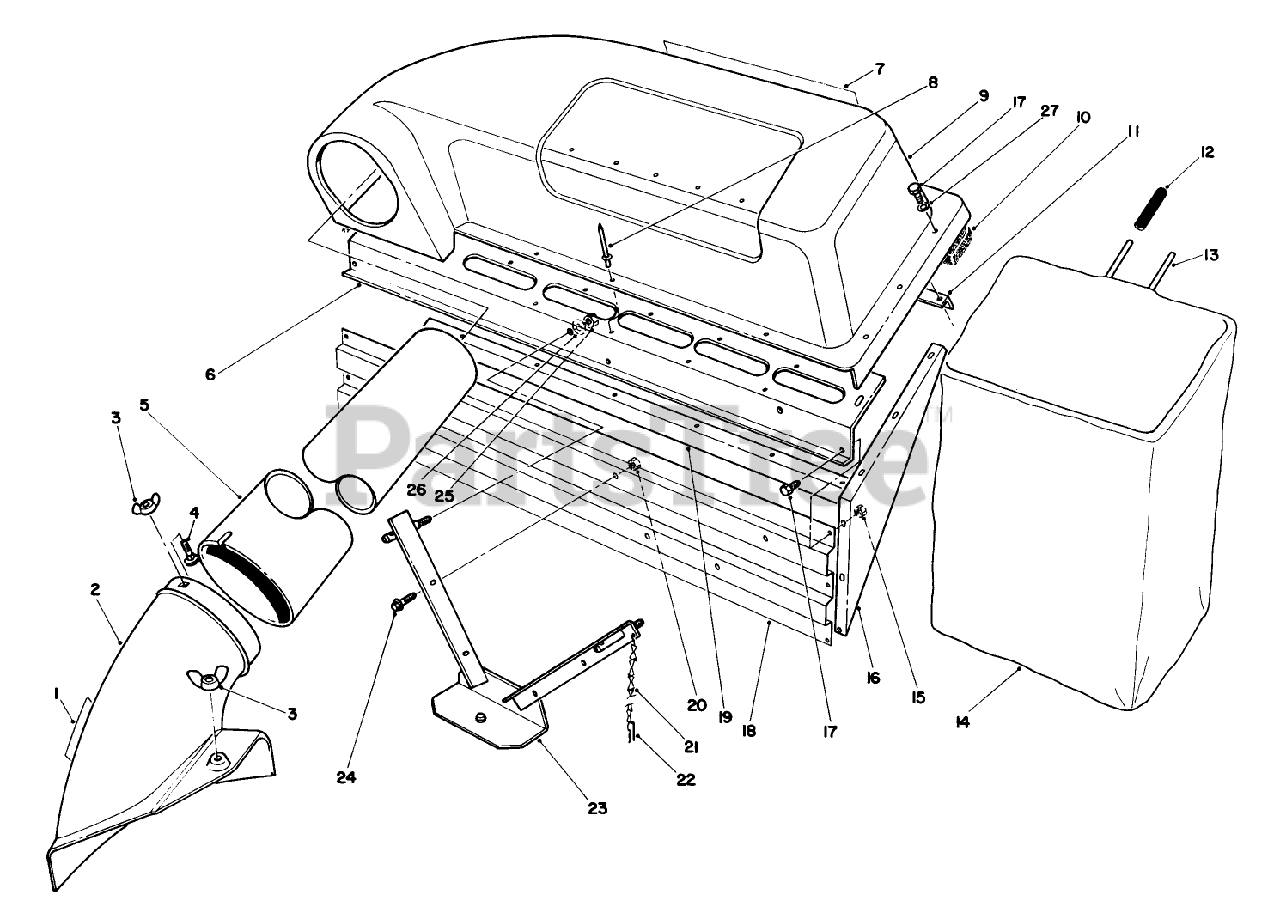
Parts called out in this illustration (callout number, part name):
3	NUT-WING SPECL
4	BOLT-CARR
6	COVER SUPT BAFFLE *B
7	TWIN BAGGER DECAL
8	RIVET-POP
9	COVER
10	FOAM SEAL
11	BAG FRAME BRKT
12	GRIP-HANDLE, BAG
13	BAG FRAME
15	NUT-LOCK, NI
17	SCREW-HH
18	MUFFLER SHIELD *
19	BAG SUPPORT CHANNEL
20	NUT-LOCK, NI
22	PIN-HAIR
24	SCREW-HH
26	WASHER-FLAT
27	WASHER-FLAT
